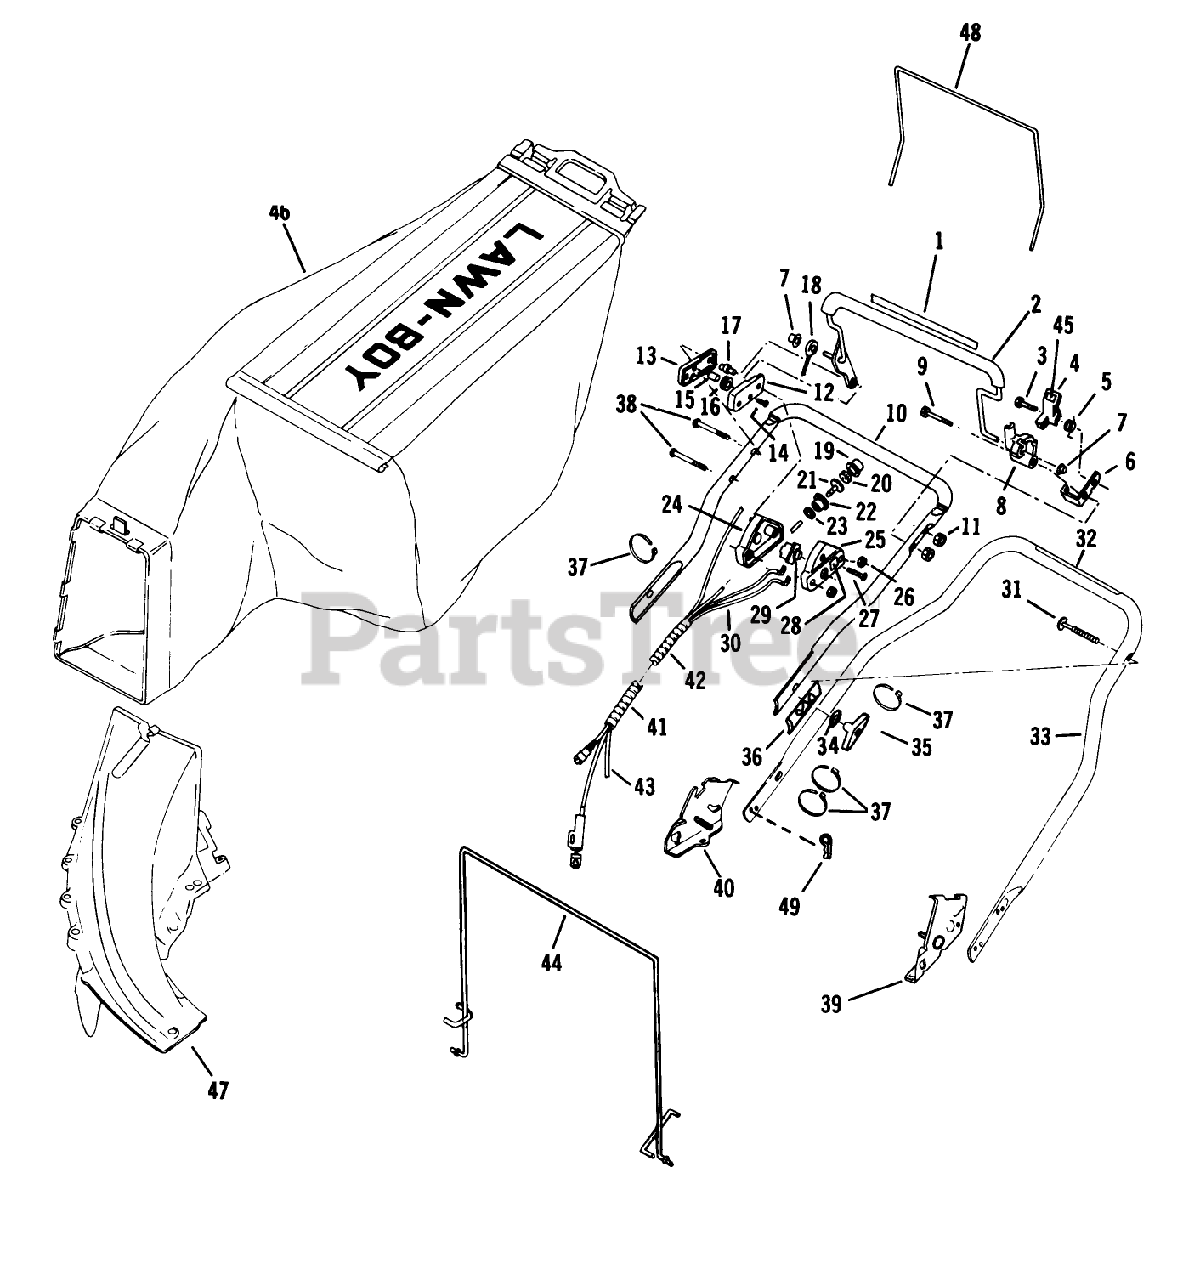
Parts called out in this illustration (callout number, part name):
9	BOLT-SHOULDER
11	LOCKNUT E
14	SCREW LAWRENCE
15	PIN SKF
20	FILTER S
23	LOCKNUT S
26	NUT C/LOCK E
29	SWITCH AY
31	BOLT QUALITY
34	WASHER-CURVED
35	NUT-WING
36	BRACKET R/B 613462
44	HANGER AY
49	HAIR PIN
